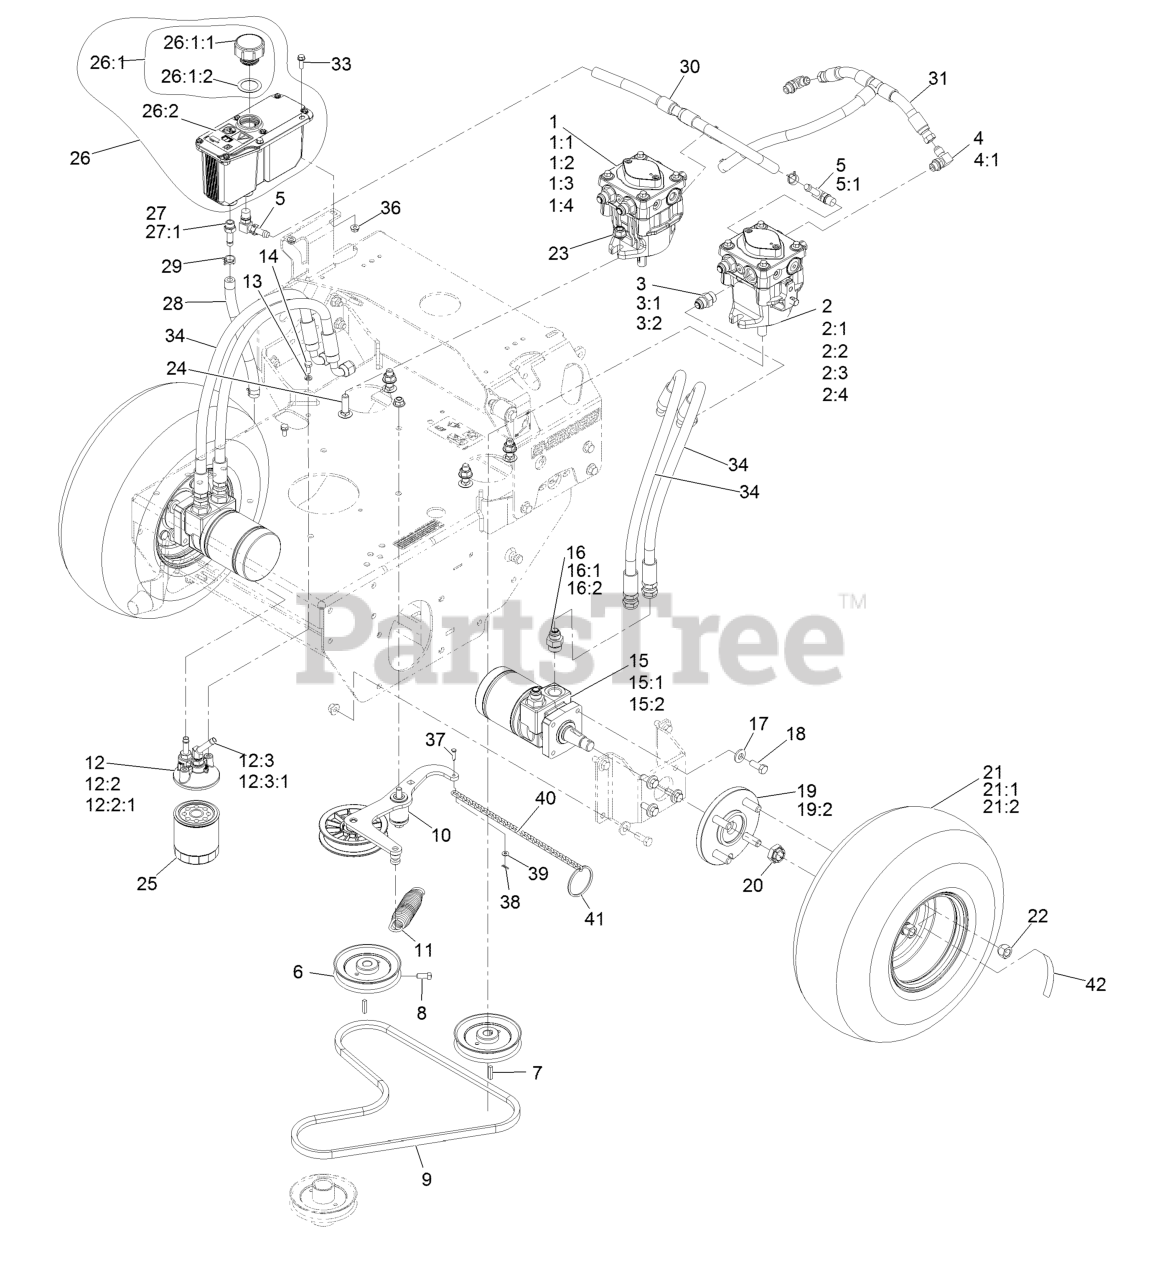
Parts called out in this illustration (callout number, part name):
1	RH HYD Pump ASM
1:1	Input Shaft Kit
1:2	Bearing-Thrust
1:3	Cylinder Block Kit
1:4	Seal Overhaul Kit
2	LH HYD Pump ASM
2:1	Input Shaft Kit
2:2	Bearing-Thrust
2:3	Cylinder Block Kit
2:4	Seal Overhaul Kit
3	Adapter-Straight
3:1	O-Ring-SAE #8
3:2	O-Ring-37 Flare #8
4	Fitting-Elbow, 90 DEG
4:1	O-Ring
5	Fitting-Elbow, 90
5:1	O-Ring
6	Sheave ASM
7	Key-5Mm X 5Mm X 25Mm
8	Screw-Set, SQH 5/16-18 X 3/4
9	Belt
10	ASM, Pump Idler
11	Spring-Extension
12	ASM, Filter Head
12:2	Adapter-Straight
12:2:1	O-Ring
12:3	Fitting-Barbed, 45 DEG
12:3:1	O-Ring
13	Washer-Lock 1/4 Heavy
14	Screw-HH 1/4-20 X 5/8
15	HYD Motor ASM
15:1	Seal Kit
15:2	Bearing And Seal Kit
16	Adapter-Straight
16:1	O-Ring
16:2	O-Ring-37 Flare #8
17	Washer-Spring Disc 3/8
18	Screw-HH 3/8-16 X 1
19	Wheel Hub ASM
19:2	Stud-Wheel
20	Nut-Lock
21	Wheel And Tire ASM
21:1	Tire-Turfmaster
21:2	Rim-Wheel
22	Nut-Lug 1/2-20
23	Nut-HF, NI
24	Bolt-Carriage 7/16-14 X 1 1/2
25	Element, Oil Filter
26	ASM, HYD Reservoir
26:1	Reservoir-HYD
26:1:1	Cap-Reservoir, HYD
26:1:2	Gasket-Cap
26:2	Decal-Warning
27	Adapter-Straight
27:1	O-Ring
28	Hose-Charge
29	Clamp-Hose 11/16
30	Hose-Case Drain
31	Hose-Charge
33	Screw-Machine 1/4-20 X 3/4
34	HYD Hose ASM
36	Nut-Whizlock 1/4-20
37	Pin-Clevis
38	Pin-Hair
39	Washer-Plain
40	Chain-Link, Twist
41	Ring-Split
42	Decal-Torque Wheel Lug-Hub
